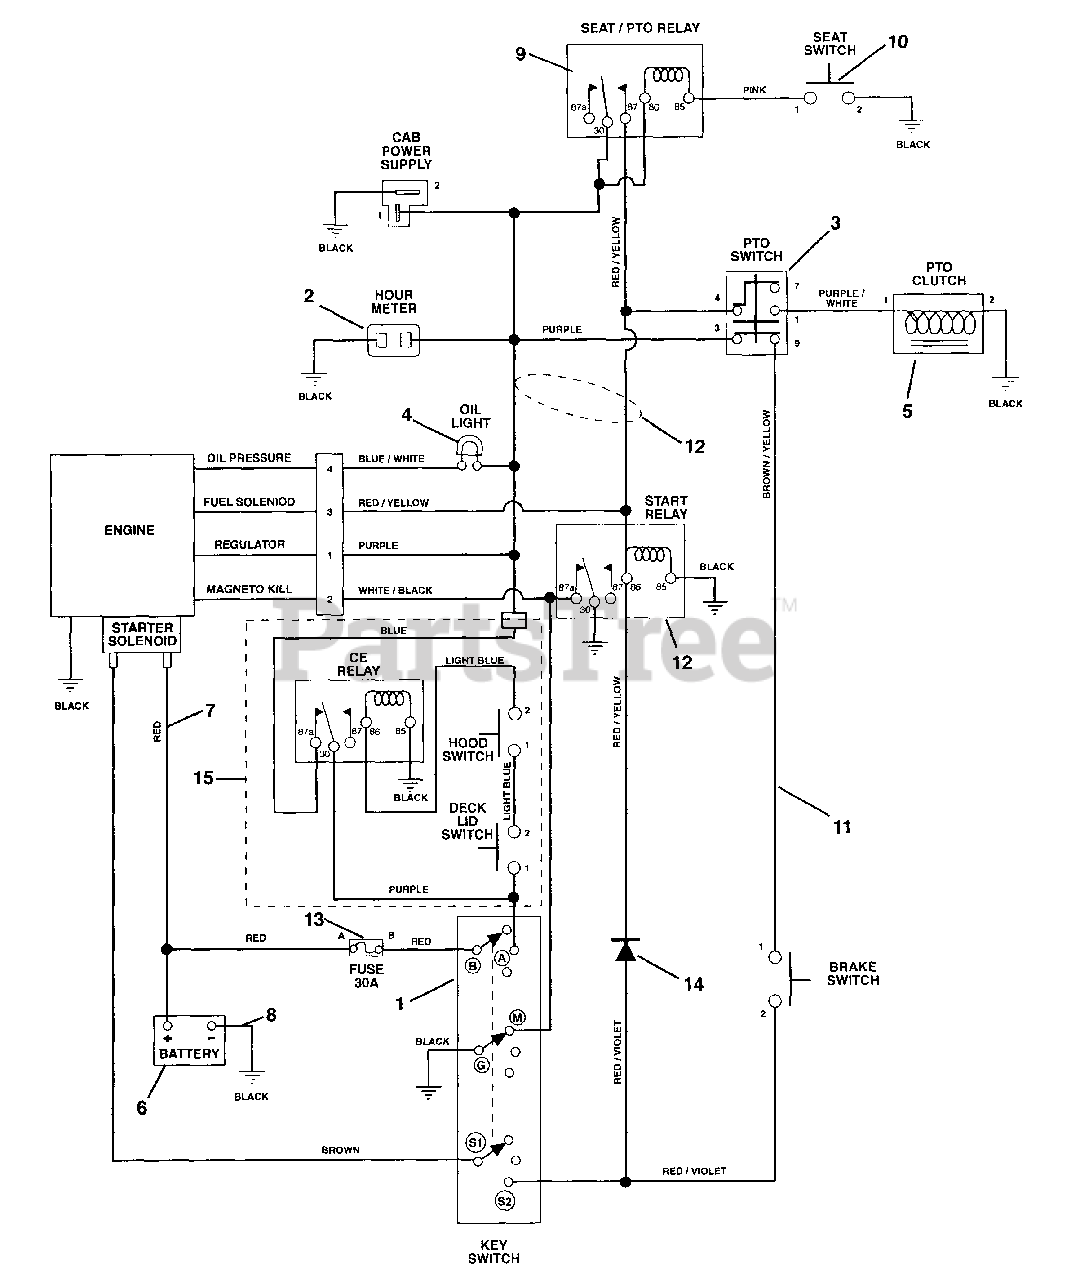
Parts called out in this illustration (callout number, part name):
1	Key Switch
2	Hour Meter
3	Switch-Clutch With Retainer Ring
4	Light-Indicator
5	Electric Clutch
6	Battery with Tube
7	Cable-Battery To Solenoid
8	Ground Cable
9	Relay
10	Seat Switch
11	Switch-Single Pole
12	Harness-Kohler
14	Molded Diode Plug-Black 1-Amp
15	Harness-CE Adapter
